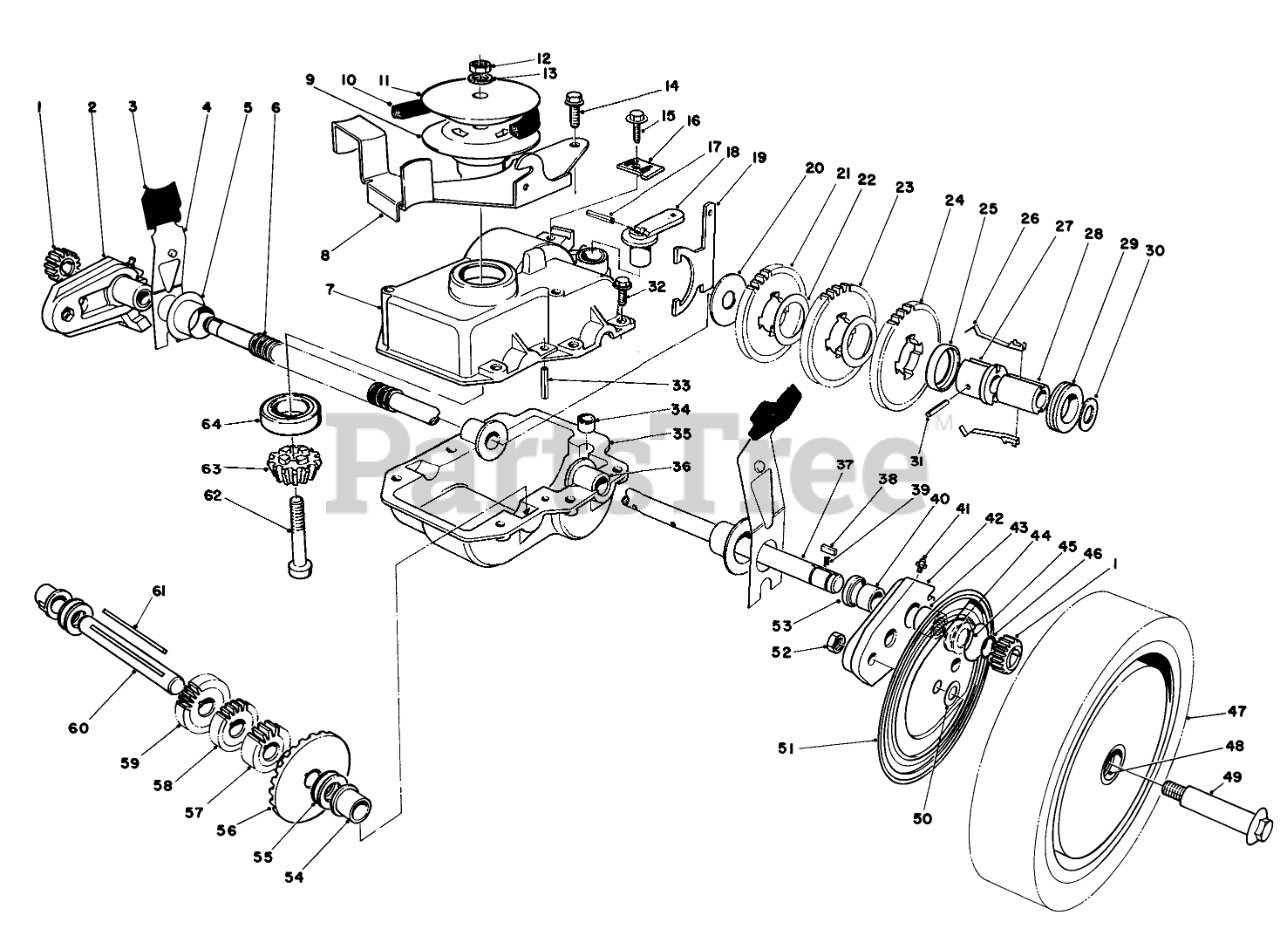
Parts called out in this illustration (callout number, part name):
1	GEAR-PINION
2	Pivot Arm Assembly-R.H. (Incl. Ref. #40, 41, 43 & 53)
3	KNOB-ARM
4	SPRING ARM ASM SP
5	CAP-END
6	CONDUIT-CONVOLUTED, SPLIT
7	Case-Upper
8	BELT GUIDE BRKTB
9	PULLEY-LOWER HALF
10	V-BELT
11	PULLEY-UPPER HALF
12	NUT-LOCK, NI
13	WASHER-FLAT
14	SCREW
15	SCREW-HWHTF
16	Cable Clamp
17	PIN-COIL
18	LEVER-SHIFT
19	Shift Yoke
20	WASHER
21	GEAR-38T
22	WASHER
23	GEAR-42T
25	KEY RETAINER
26	KEY-SHIFT
27	Body-Sleeve
28	SLEEVE
29	COLLAR-SHIFT
30	WASHER-PLAIN
31	PIN-SPRING
32	SCREW-HWHTF
33	ROLL PIN 3/16 X 1 IN
34	BUSHING-YOKE
35	LOWER GEAR CASE CAST
36	Bushing-Output Shaft
37	Output Shaft
38	KEY RECTANGULAR
39	SPRING-COMPRESSION
40	BUSHING
41	FITTING-GREASE
42	Pivot Arm Assembly-L.H. (Incl. Ref. #40, 41, 43 & 53)
43	BEARING-ROLLER
44	INNER THRUST WASHER
45	WASHER-THRUST, OUTER
46	RING-RETAINING
47	Wheel, Tire & Gear Assembly (Incl. Ref. #48)
48	BUSHING
49	WHEEL BOLT
50	WASHER
51	WHEEL COVER
52	NUT-LOCK
53	SEAL-OIL
54	BUSHING
55	WASHER-THRUST
56	BEVEL GEAR
57	GEAR-12T
58	GEAR-14T
59	GEAR-18T
60	INTERMEDIATE SHAFT
61	Key Square
62	Screw-Socket Hd
63	BEVEL PINION
64	BEARING-BALL
